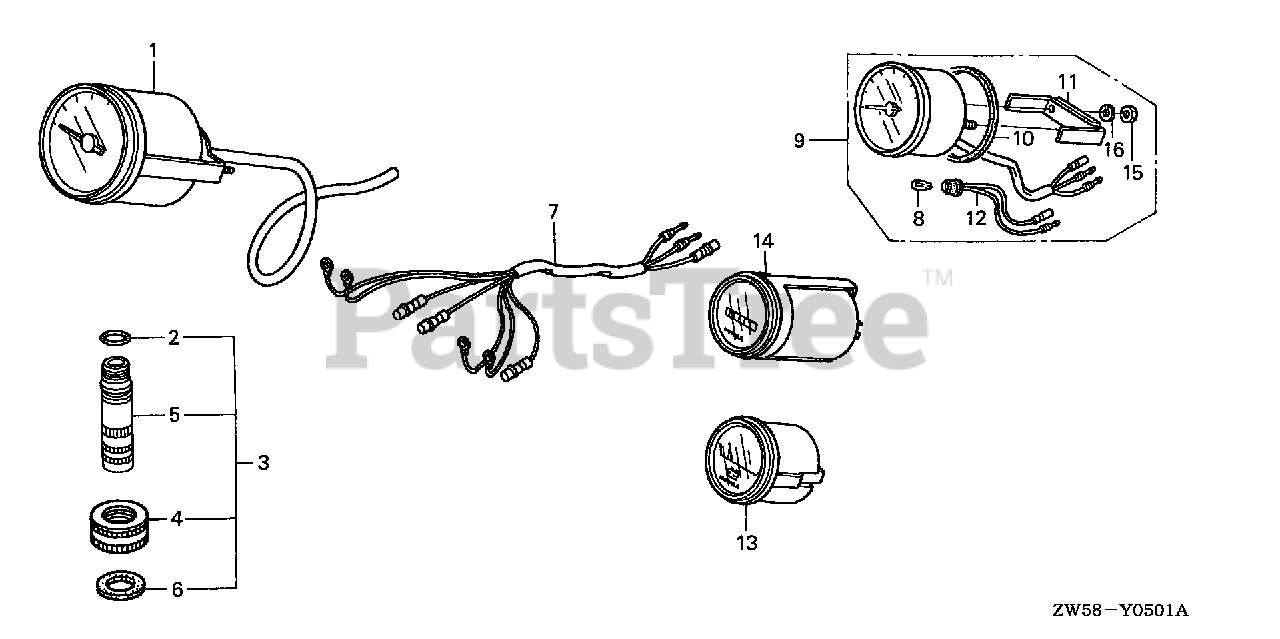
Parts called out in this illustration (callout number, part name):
1	SPEEDOMETER KIT
2	O-RING (11.8X2.4)
3	JOINT ASSY., HOSE
4	NUT, WATER MOUTH
5	JOINT ASSY., HOSE
6	SEAT, WATER MOUTH
7	HARNESS ASSY., METER (B)
8	BULB, WEDGE BASE (T10) (12V 1.7W) (STANLEY)
9	TACHOMETER ASSY.
10	GASKET
11	BRACKET
12	SOCKET
13	METER ASSY., VOLT (NOT AVAILABLE)
14	METER ASSY., HOUR L.C.D.
15	NUT, HEX. (5MM)
16	WASHER, SPRING (5MM)
